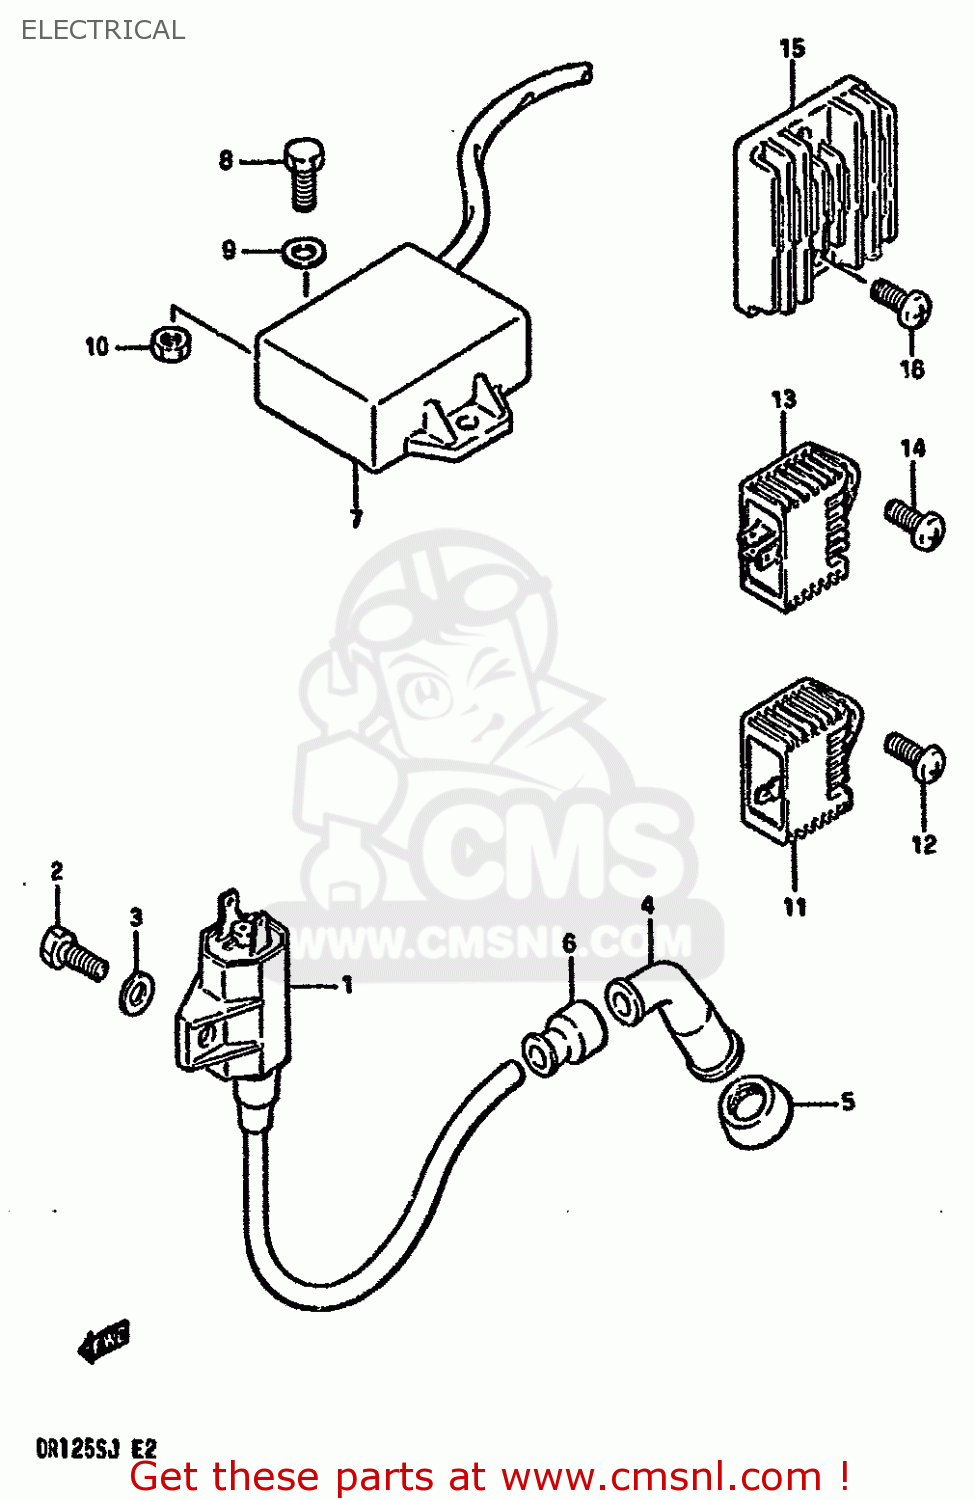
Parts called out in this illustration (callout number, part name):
1	COIL ASSEMBLY,IGNITION
2	BOLT
3	WASHER, LOWER
4	CAP,SPARK PLUG
5	SEAL,SPARK PLUG CAP
6	SEAL,SPARK PLU
7	CDI UNIT
8	BOLT
9	WASHER, LOWER
10	NUT
11	REGULATOR ASSY,VOLTAGE
12	SCREW
13	RECTIFIER ASSY,REGULATOR
14	SCREW
15	RECTIFIER ASSY
16	SCREW
